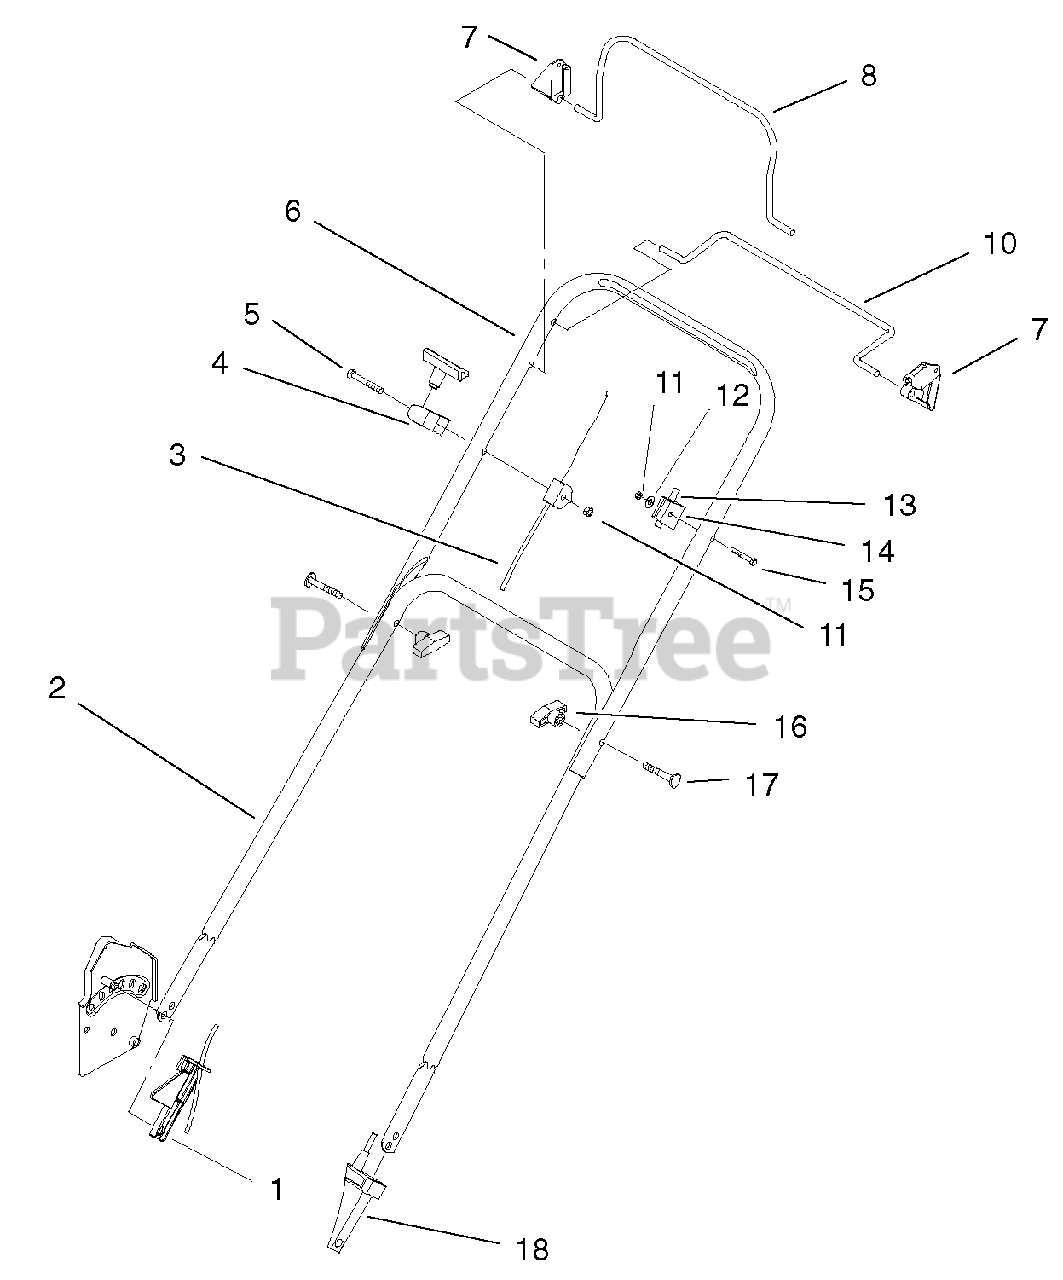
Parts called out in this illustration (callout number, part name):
1	GUARD-CABLE
2	HANDLE - LOWER
3	BRAKE CABLE ASM
4	GUIDE-ROPE
5	SCREW-HH
6	HANDLE-UPPER
7	STOP-PIVOT
8	BAIL - BRAKE
10	BAIL-CONTROL
11	NUT-LOCK, NI
12	WASHER-FLAT
13	CABLE-GROUND SPEED
14	ANCHOR-UPPER, CABLE
15	SCREW-HANDLE
16	KNOB-HANDLE
18	ANCHOR - CABLE
19	HANDLE-STARTER
